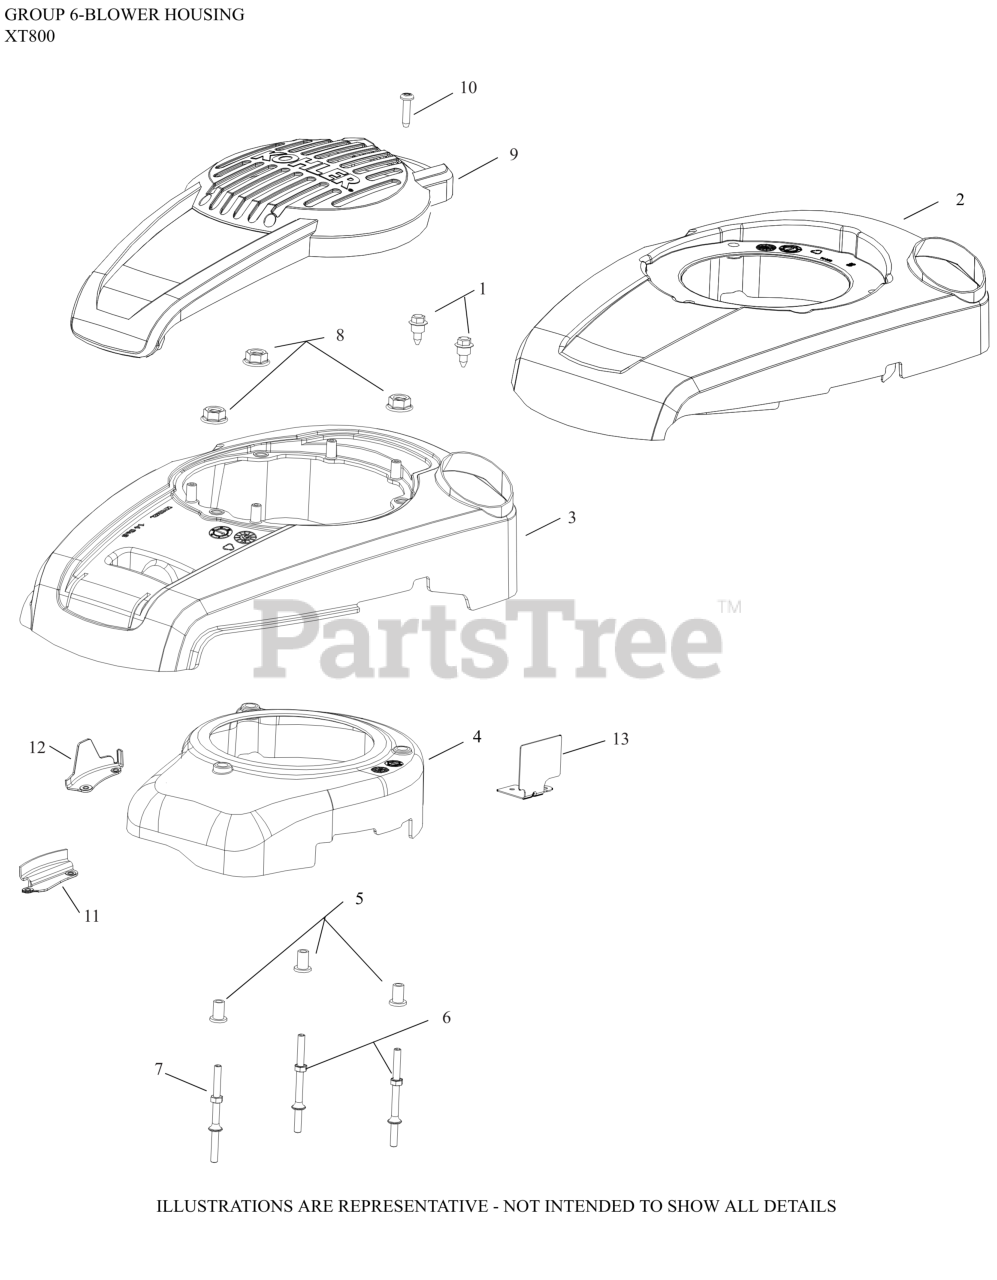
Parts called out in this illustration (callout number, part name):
2	COVER, ENGINE
6	STUD-USE 14 072 26-S
7	STUD-USE 14 072 25-S
8	NUT, HEX FLANGE (M6) - USE 14 100 16-S
